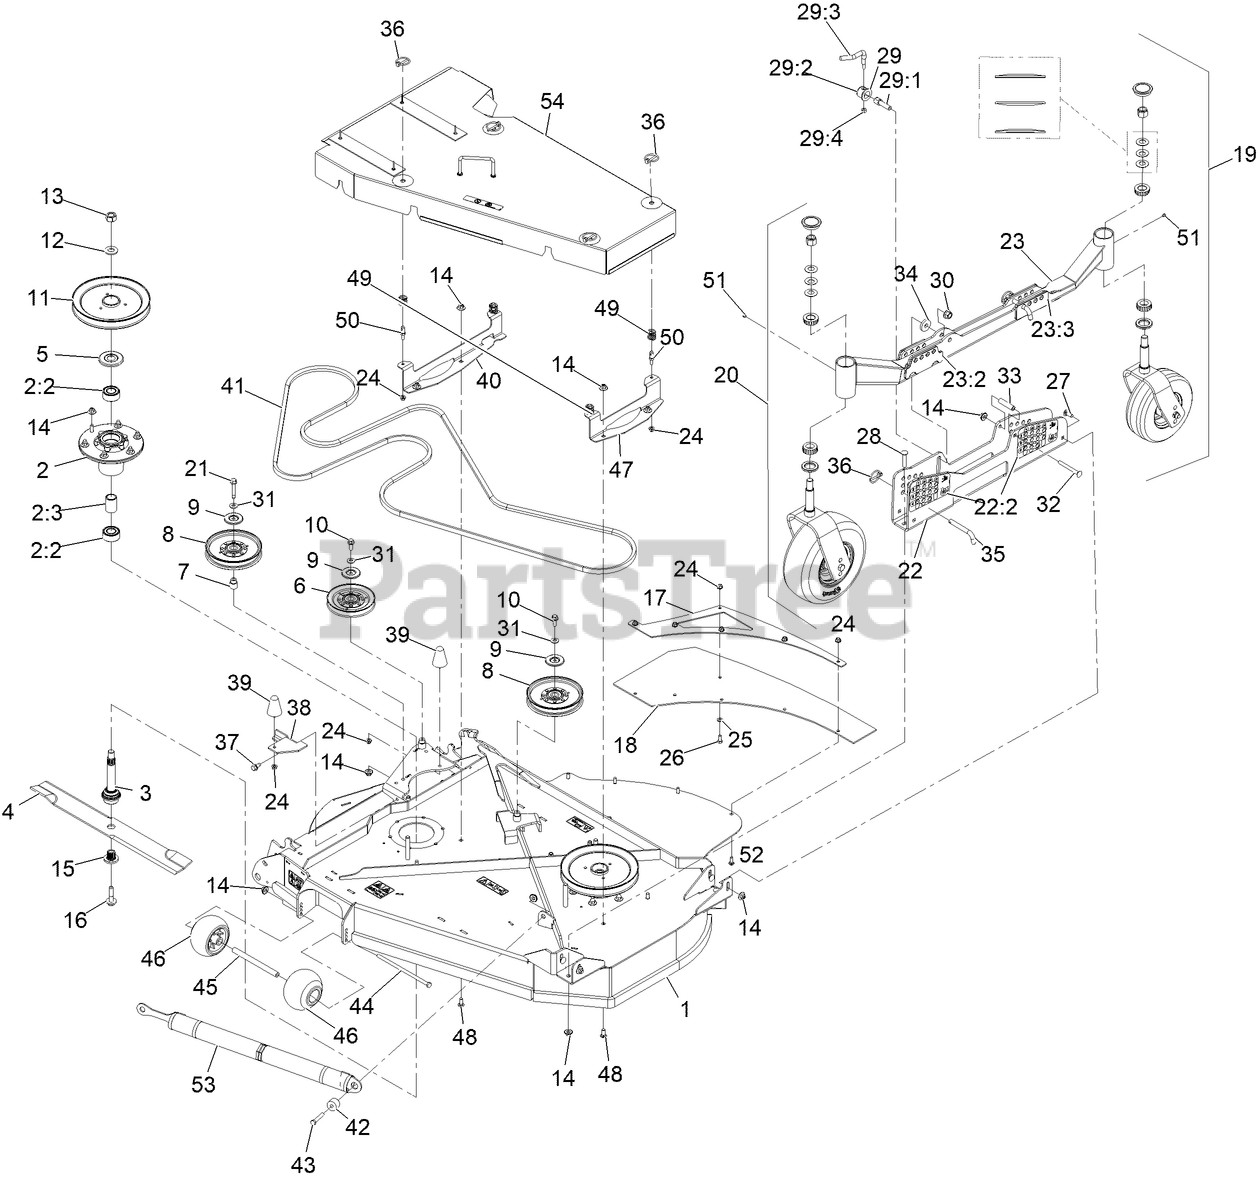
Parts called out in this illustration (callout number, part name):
1	ASM-LH Wing Deck 144
2	ASM-CUTTER HSG
2:2	BEARING-3205 TRASHGUARD
2:3	SPACER-BEARING
3	ASM-SPINDLE AND SEAL
5	GUARD-BEARING, TOP
6	IDLER-V
7	BUSHING-IDLER
8	IDLER-PULLEY
9	SHIELD-DUST
10	SCREW-HHF 3/8-16 X 1
11	SHEAVE-SINGLE 96RD
13	NUT-HEX
14	Nut-Nyloc 3/8-16 Flg
15	BUSHING,SPLINED
16	SCREW,SEMS 1/2-20 X 2.19
17	SUPPORT-LH REAR GUARD
18	GUARD-LH REAR WING
19	Caster/Wheel ASM
21	SCREW-HHF
22	ASM-CHANNEL, HOC LH
22:2	DECAL-HEIGHT OF CUT-LH
23	ASM-LH GAUGE WHEEL ARM
23:2	PLATE-GUIDE, FRONT
23:3	PLATE-GUIDE, REAR
24	NUT-HF, NI
25	WASHER-PLAIN
26	SCREW-HH
27	BOLT-CARR
28	SCREW-CARR
29	LEVER ASM
29:1	SCREW-LOCK
29:2	CAP-LOCK
29:4	NUT-LOCK, NI
30	Nut-Lock 1/2-13
31	WASHER-BELLEVILLE
32	SCREW-CARR
35	PIN-HOC
36	PIN-LYNCH
37	SCREW-HWH
38	BRACKET-COVER RETAINER
39	BUMPER-RUBBER
40	BRACKET-SHIELD MOUNT, OUTER LONG
42	BUSHING-LIFT SPRING
43	SCREW-HH
44	SCREW-HH
45	SPACER-WHEEL
46	ROLLER-SCALP, ANTI
47	BRACKET-SHIELD MOUNT, OUT
48	BOLT-CARR
50	PIN, SPRING
52	SCREW-CARR
53	ASM-WEIGHT-TRANSFER-SPRING
54	ASM-BELT SHIELD
